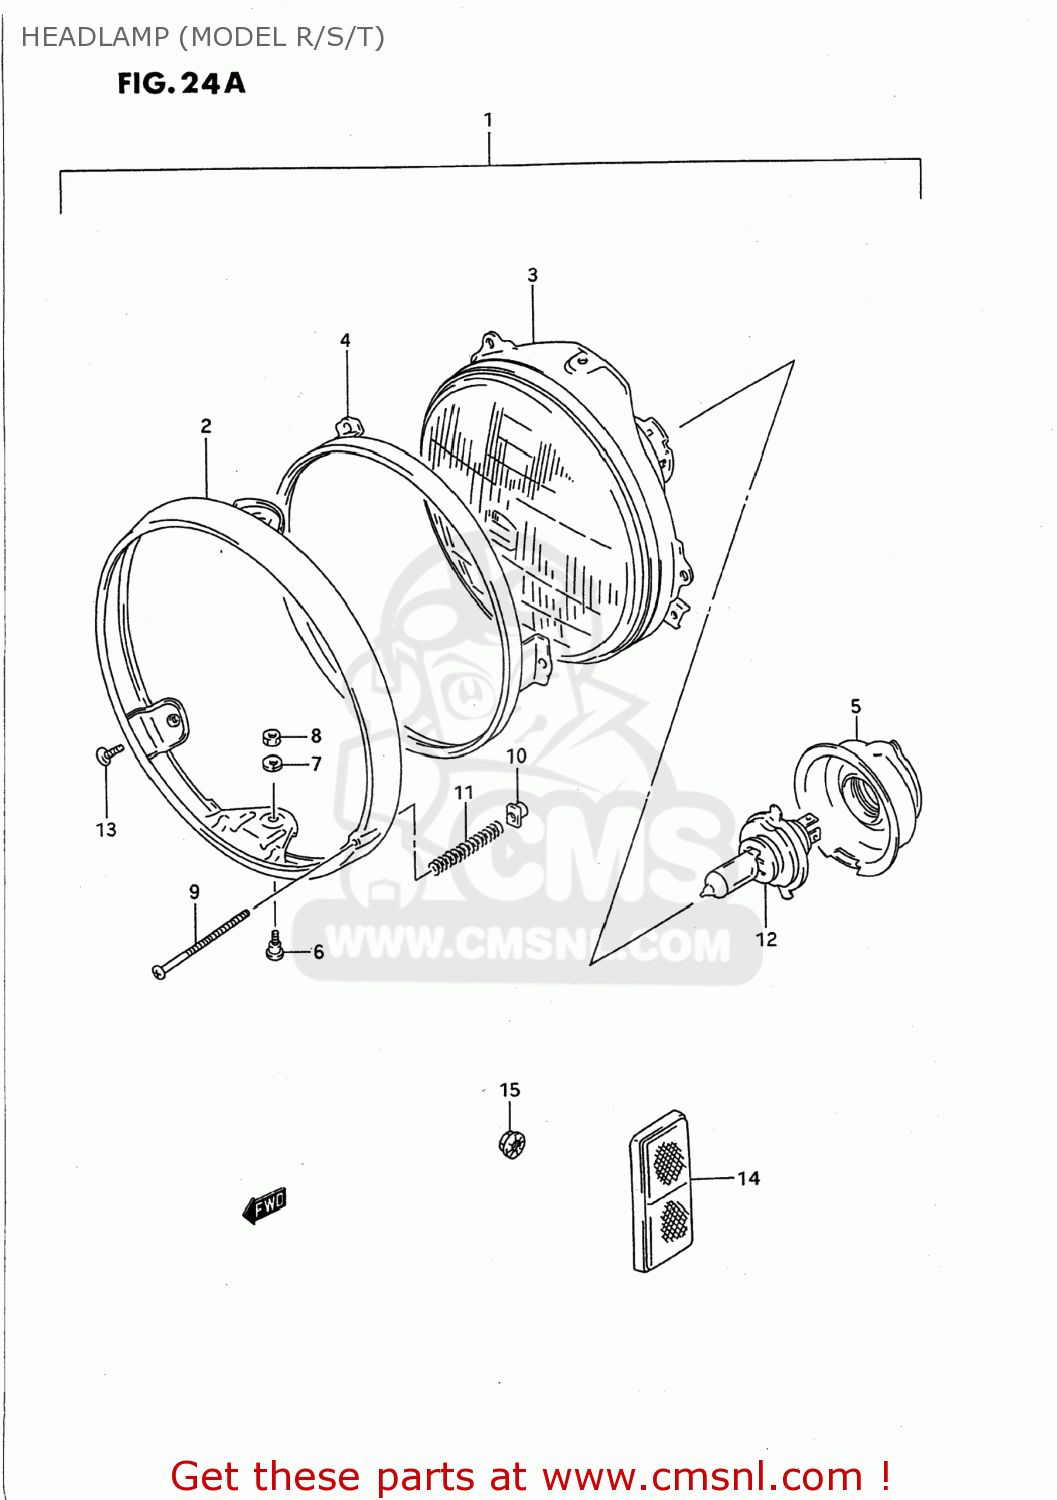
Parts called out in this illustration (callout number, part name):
1	HEADLAMP ASSEMBLY
2	RIM,HEADLAMP
3	LAMP UNIT
4	RING
5	COVER,SOCKET
6	H/LAMP LENS UNIT FITING SCRE
7	WASHER,LOCK
8	NUT
9	SCREW
10	NUT
11	SPRING,ADJUSTING
12	BULB(12V60/55W,H4)
13	SCREW
14	REFLEX REFLECTOR,FR SIDE
15	NUT
